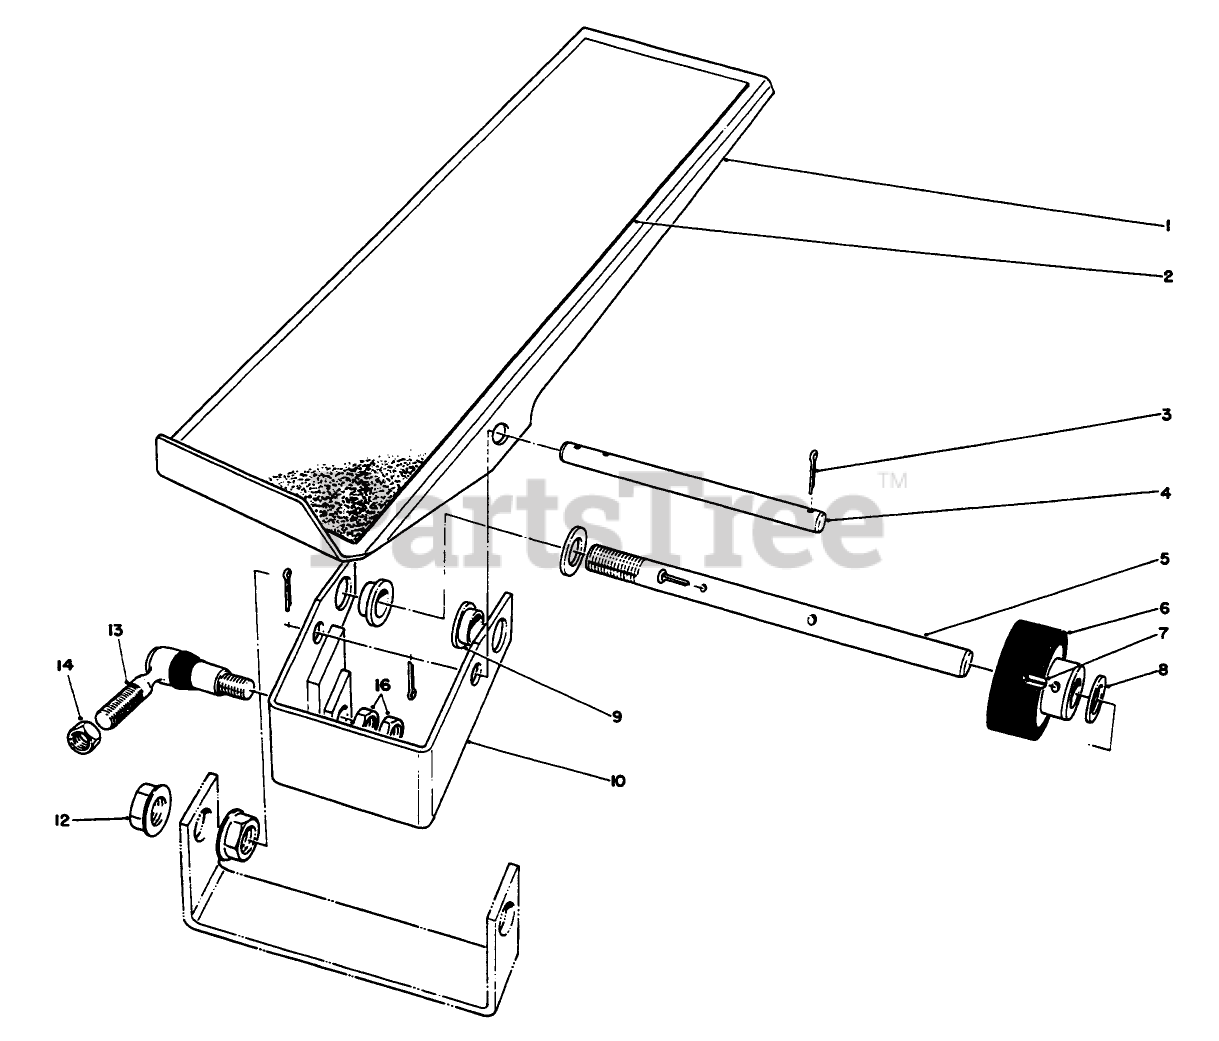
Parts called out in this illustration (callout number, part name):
1	Pedal-Traction
2	TRACTION PEDAL PAD
3	PIN-COTTER
4	PEDAL PIVOT PIN
5	Shaft-Traction Pedal
6	FRICTION WHEEL ASM
7	PIN-ROLL, SLOTTED
8	WASHER-FLAT
9	BUSHING-FLANGE
10	Pivot Bracket Assembly (Incl. Ref. #9)
11	WASHER-LOCK
12	NUT-HHF
13	RH BALL JOINT ASM
14	NUT-JAM
16	NUT-HJ
